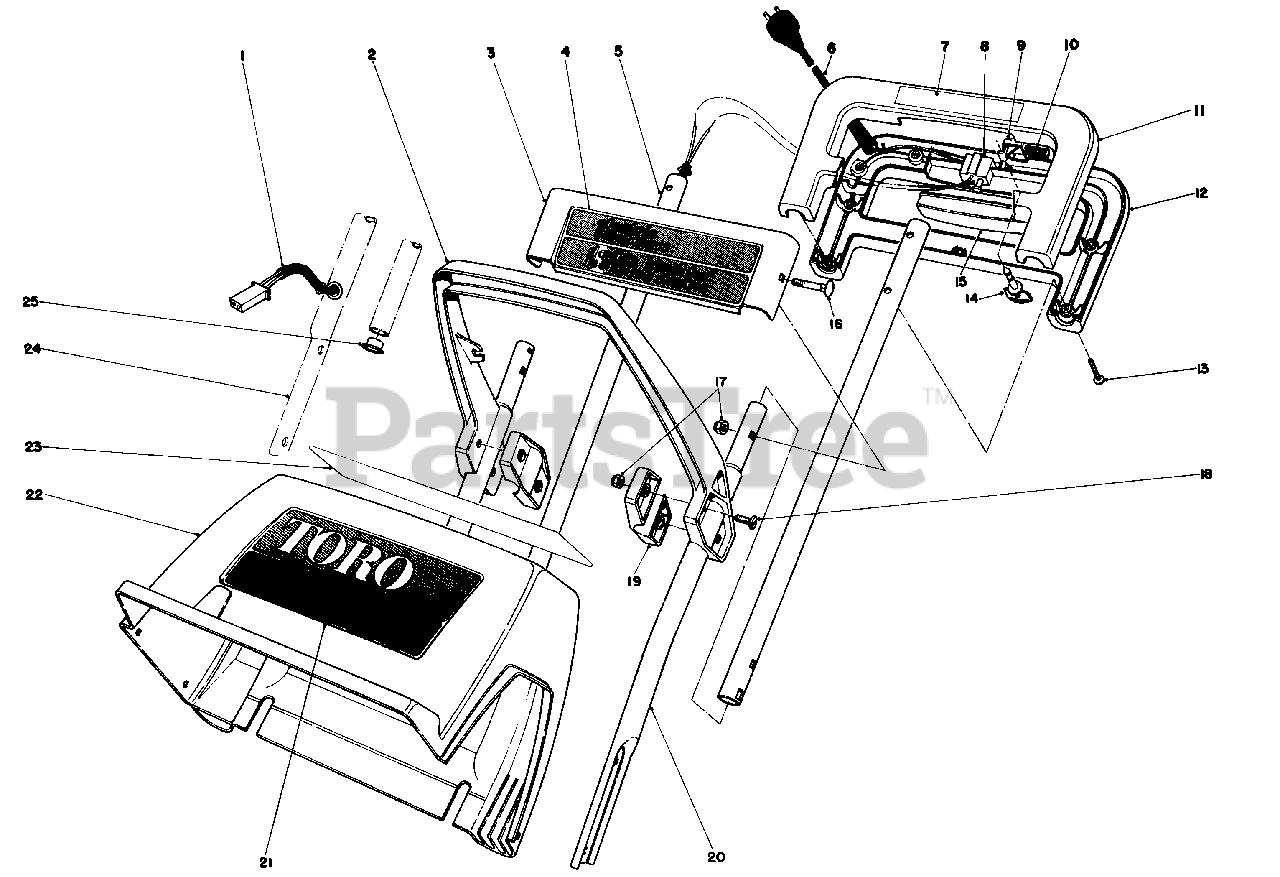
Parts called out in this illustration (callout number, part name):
1	Wire Harness
2	Middle Handle
3	Escutcheon Plate
4	Decal-Electric
5	Upper Tube
6	Cord Supply
7	Decal-Handle
9	Lockout-Switch
10	Spring Compression
11	Handle-Upper Control
12	Handle-Lower Control
13	Screw
15	Switch Bar
16	Carriage Bolt
18	Screw-Round Head
19	Clamp-Middle Handle
20	Handle-Lower L.H.
21	Decal-Toro S-120
22	Shroud-S-120
23	Decal-U.L.
24	Handle-Lower R.H.
25	Snap Bushing
